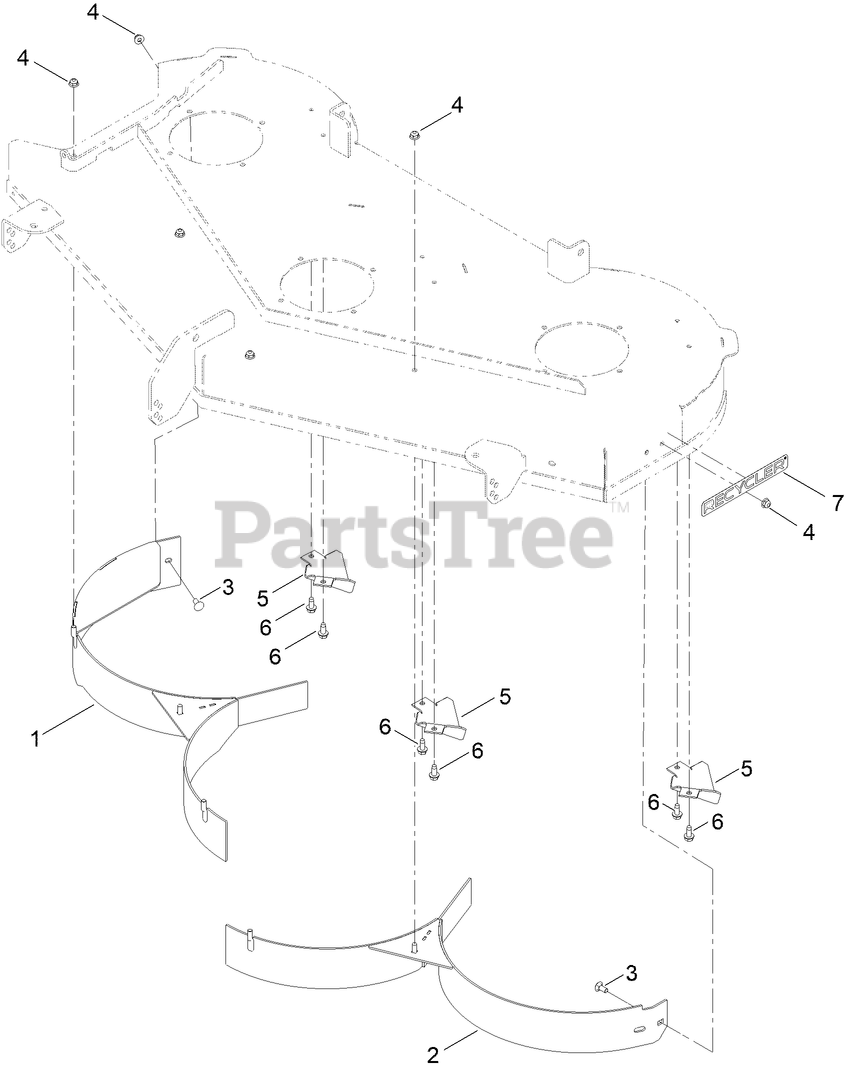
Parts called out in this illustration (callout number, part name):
1	54" BAFFLE ASM [WELDED] [BLACK]
2	54" BAFFLE ASM [WELDED] [BLACK]
3	BOLT-CARR
4	NUT-HF
5	KICKER-FLANGED
6	SCREW-HWHTF
